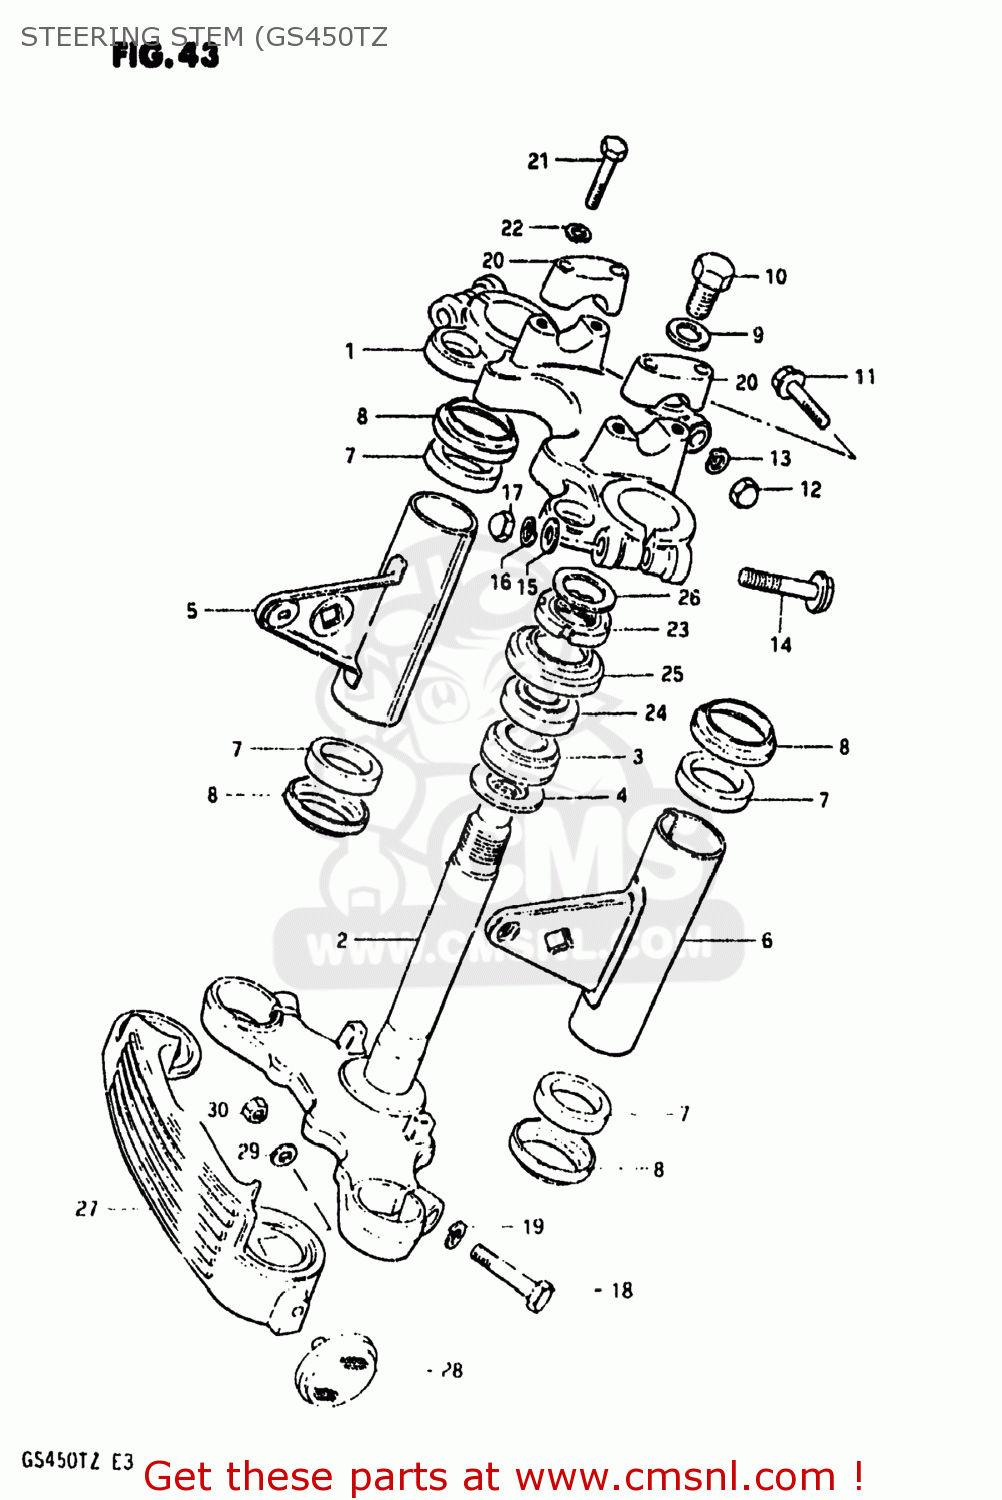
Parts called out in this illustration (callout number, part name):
1	HEAD,STEERING STEM
2	STEM,STEERING
3	BEARING
4	WASHER,THRUST
5	BRACKET,HEADLAMP,RIGHT
6	BRACKET,HEADLAMP,LEFT
7	CUSHION,HEADLAMP BRACKET
8	CAP,HEADLAMP BRACKET
9	WASHER
10	BOLT(12X20)
11	BOLT
12	NUT
13	LOCK WASHER
14	BOLT 10X55
15	WASHER
16	LOCK WASHER
17	NUT
18	BOLT 10X40
19	LOCK WASHER
20	HOLDER,HANDLE UPR
21	BOLT
22	WASHER,LOCK,8.
23	NUT,STEERING STEM
24	TAPER,ROLLER BEARING
25	DUST SEAL,STEERING,UPPER
26	WASHER(18.5X24X1)
27	COVER,FRONT FORK
28	REFLEX REFLECTOR,RR
29	WASHER
30	NUT
